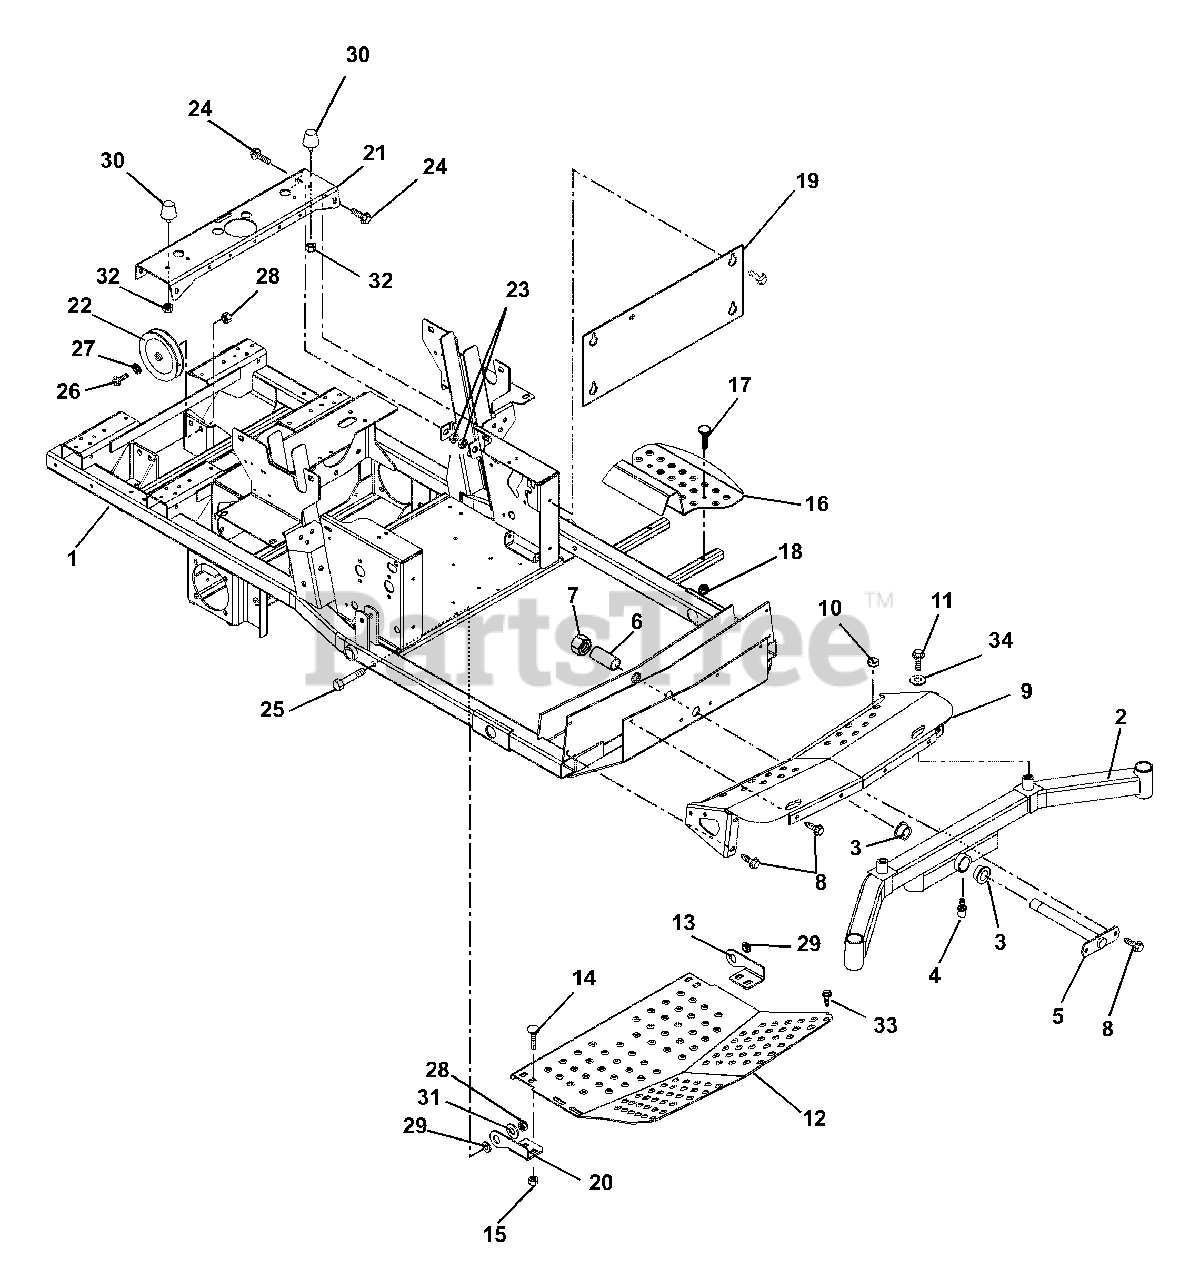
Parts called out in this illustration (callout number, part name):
1	Weldment, Frame
2	Weldment, Front Axle
3	Bushing, Flange 1.020 x 1.385 x .75 x 1.75
4	Fitting, Lube .25-28 x .256
5	Pin, Axle
7	Nut, Locking Nylon 1.0-14
8	Screw, Tapping .38-16 x .75
9	Weldment, Axle Cover
10	Button, Bumper
11	Bolt, Hex .50-20 x 1.00 Grade 5
12	Panel, Inspection
13	Hinge, Footboard Left Hand
14	Bolt, Round Head Square Neck .38-16 x 1.00 Grade 5
15	Nut, Locking Top Flange .38-16
16	Step, Ingress
17	Bolt, Round Head Square Neck .31-18 x 1.75 Grade 5
18	Nut, Locking Top Flange .31-18
19	Plate, Kick
20	Hinge, Footboard Right Hand
21	Channel, Cross
22	Pulley, Idler
23	Nut, Retainer .375-16 x .37
24	Bolt, Serrated Flange Washer Head .38-16 x 1.00
25	Bolt, Hex .50-13 x 3.25 Grade 5
26	Bolt, Hex .50-13 x 2.25 Grade 5
27	Washer, Flat Steel .505 x .88 x .072
28	Nut, Locking Top Flange .50-13
29	Bushing, Flange .515 x .75 x .275 x 1.12
31	Washer, Flat Steel .563 x 1.38 x .109
32	Nut, Locking Flange .312-24
33	Screw, Tapping Hex Washer Head .38-16 x 1.00 (318, 319)
34	Washer, Flat Steel .518 x 2.00 x .105
